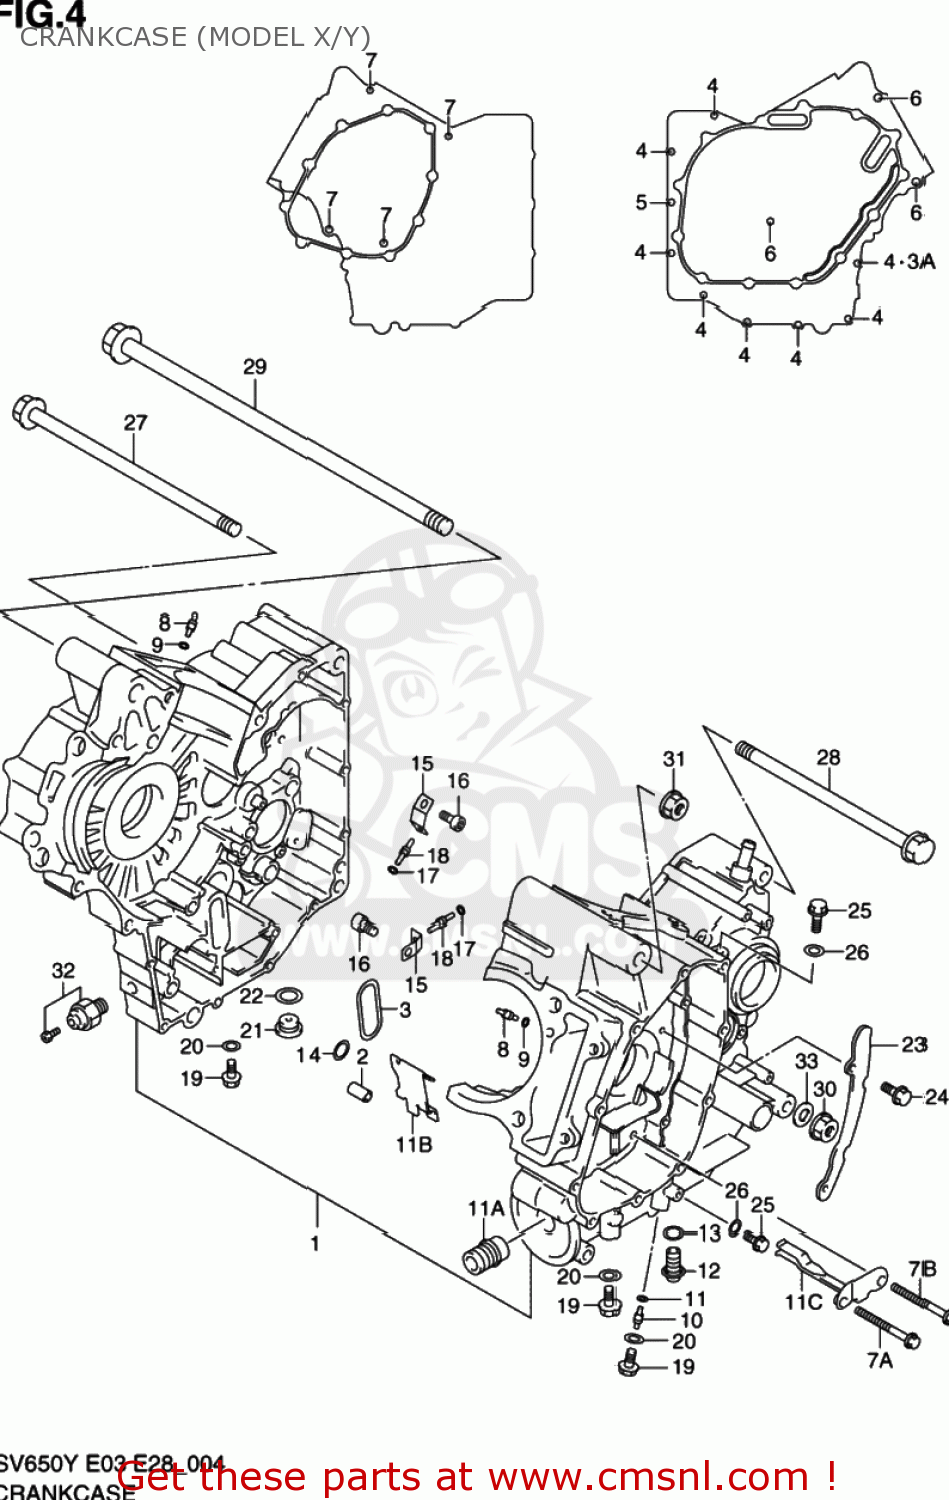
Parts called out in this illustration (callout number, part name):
1	CRANKCASE SET
2	PIN(8.4X11X20)
3	O RING,CRANKCASE
3A	GASKET(5.8X13X1.2) (NAS)
4	BOLT
5	BOLT
6	BOLT
7	BOLT
7A	BOLT,CRANKCASE(L:90)
7B	BOLT(8X95)
8	JET,AIR(14)
9	O RING(D:1.2,ID:4)
10	JET,AIR(14)
11	O RING(D:1.2,ID:4)
11A	UNION,OIL STAND
11B	PLATE,OIL
11C	PLATE,OIL
12	PLUG,12X20
13	GASKET(12.1X16.2X3.7) (NAS)
14	O RING(D:1.9,ID:12.6)
15	PLATE,PISTON COOLING JET
16	BOLT(6X12)
17	O RING(D:1.2,ID:4)
18	JET(13)
19	BOLT
20	GASKET(8.2X16X1) (NAS)
21	PLUG,16X8
22	GASKET(16X22X2) (NAS)
23	PLATE,OIL SEPARATOR
24	BOLT
25	BOLT
26	GASKET(5.8X13X1.2) (NAS)
27	BOLT(10X265)
28	BOLT 10X215
29	BOLT(12X310)
30	NUT
31	NUT 12MM
32	SWITCH ASSEMBLY,OIL PRESSURE
33	WASHER (10.5X22X2.3)
